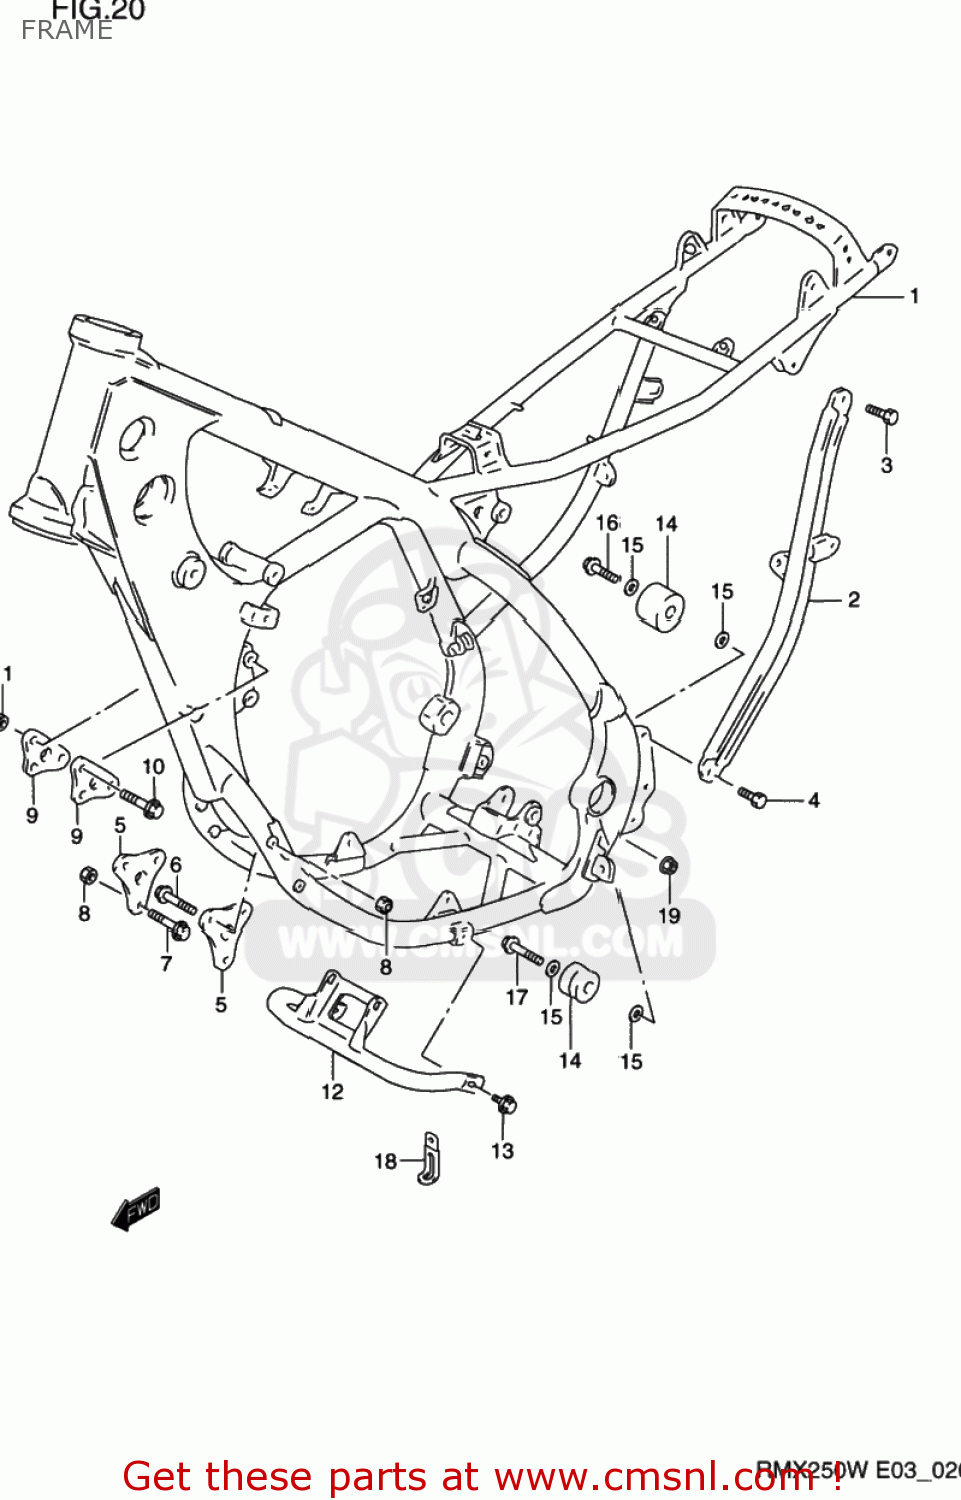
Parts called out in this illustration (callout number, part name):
1	FRAME COMP
2	TUBE,FRAME SIDE,L
3	BOLT
4	BOLT
5	PLATE,ENG MTG FR
6	BOLT
7	BOLT M8X65
8	NUT
9	PLATE,ENGINE MOUNT UPR
10	BOLT(8X45)
11	NUT
12	PROTECTOR,ENGINE
13	BOLT(8X14)
14	ROLLER,CHAIN
15	SHIM(8X12X1)
16	BOLT(8X41)
17	BOLT(8X45)
18	CLAMP(L:65)
19	NUT
